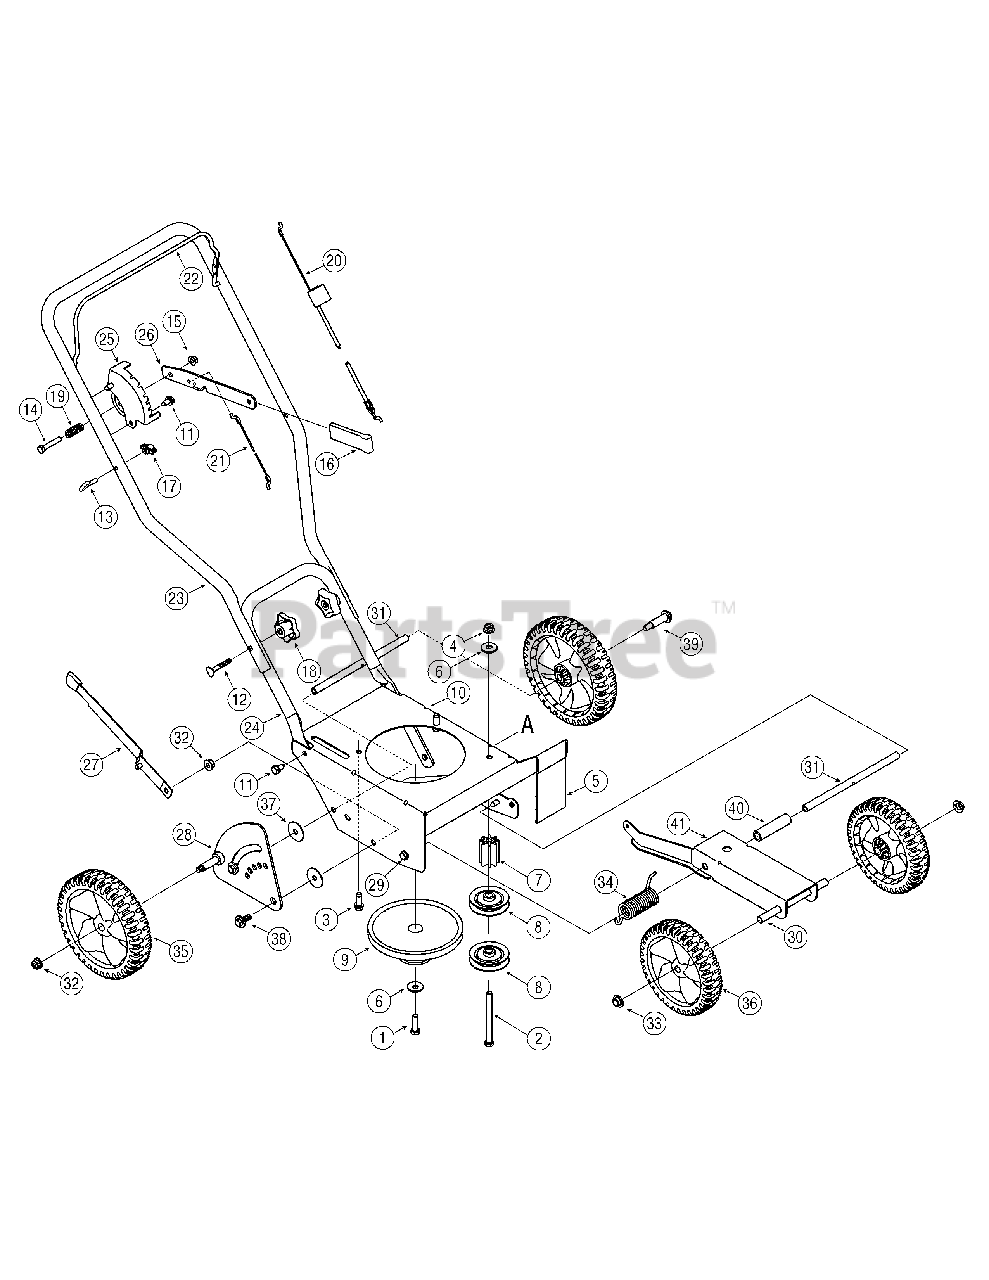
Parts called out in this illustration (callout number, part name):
1	Screw 3/8-24
2	Screw 3/8-16
3	Screw, 3/8-16
4	Flange Lock Nut, 3/8-16
5	Debris Guard
6	Bell Washer, .396 x 1.140
7	Pulley Mount Spacer
8	Flat Idler Pulley, 2.5 OD
9	Combination Flywheel Pulley
27	Curb Height Adjustment Lever
28	Curb Height Adjuster Plate
29	Hex Screw, 5/16 x 18
30	Axle Shaft .50x6.65
31	Frame Spacer, .50x9.25 (2 used)
32	Flange Nut 3/8-16
33	Push Cap 1/2" rod
